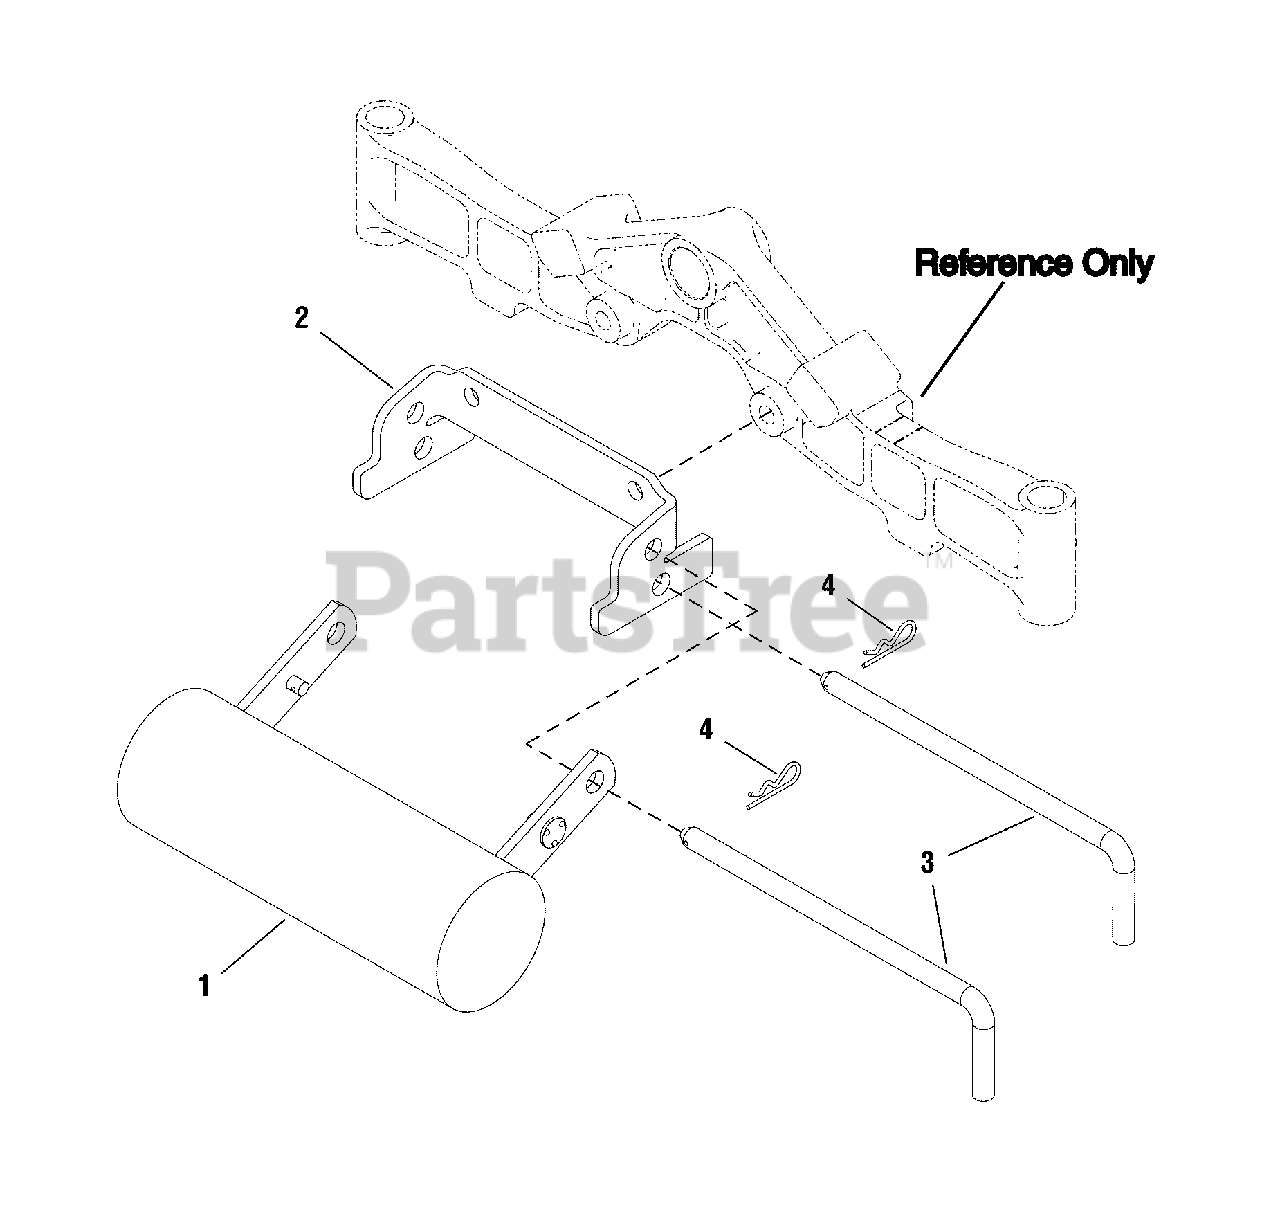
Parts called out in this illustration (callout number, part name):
1	COUNTER WEIGHT ASSEMBLY
2	HITCH, Mower Mount
3	ROD, Hitch
4	PIN, Hitch
